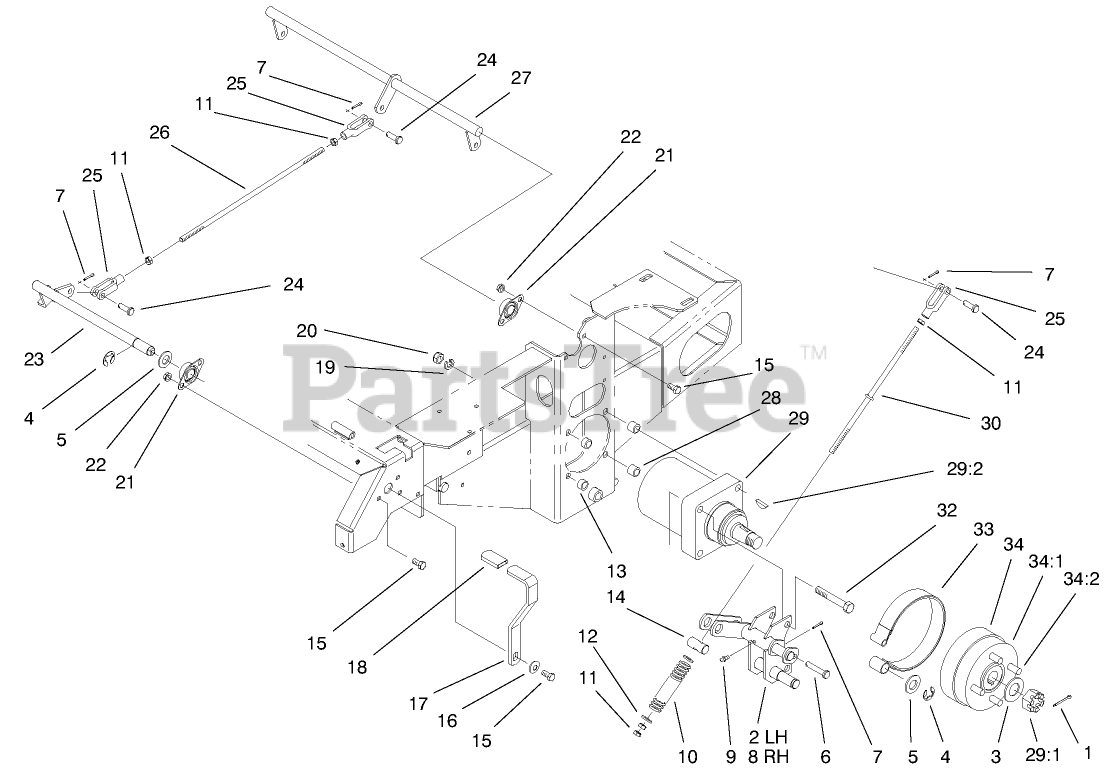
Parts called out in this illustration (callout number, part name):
1	Pin-Cotter
2	Bracket-Brake, LH
3	Spacer
4	Ring-Retaining
5	WASHER-FLAT
6	Pin-Clevis
7	PIN-COTTER
8	Bracket-Brake, RH
9	Fitting-Grease
10	Spring-Brake
11	NUT-HEX
12	WASHER-FLAT
13	Spacer
14	Pin-Trunion
15	SCREW-HH
16	Washer
17	Handle-Brake, Park
18	Grip-Brake Lever
19	WASHER-LOCK
20	NUT-HH
21	Bearing-Side Flange
22	NUT-HHF, WHIZ
23	Shaft-Brake
24	Pin-Clevis
25	Yoke-Brake Linkage
26	Linkage-Brake Handle
27	Brake Crank
28	Spacer
29	Motor-Wheel
29:1	Nut
29:2	Key-Woodruff
30	Rod-Brake
32	SCREW-HH
33	Band-Brake
34	Hub-Wheel
34	Hub And Drum ASM
34:1	Hub-Wheel
34:2	Stud-Wheel
